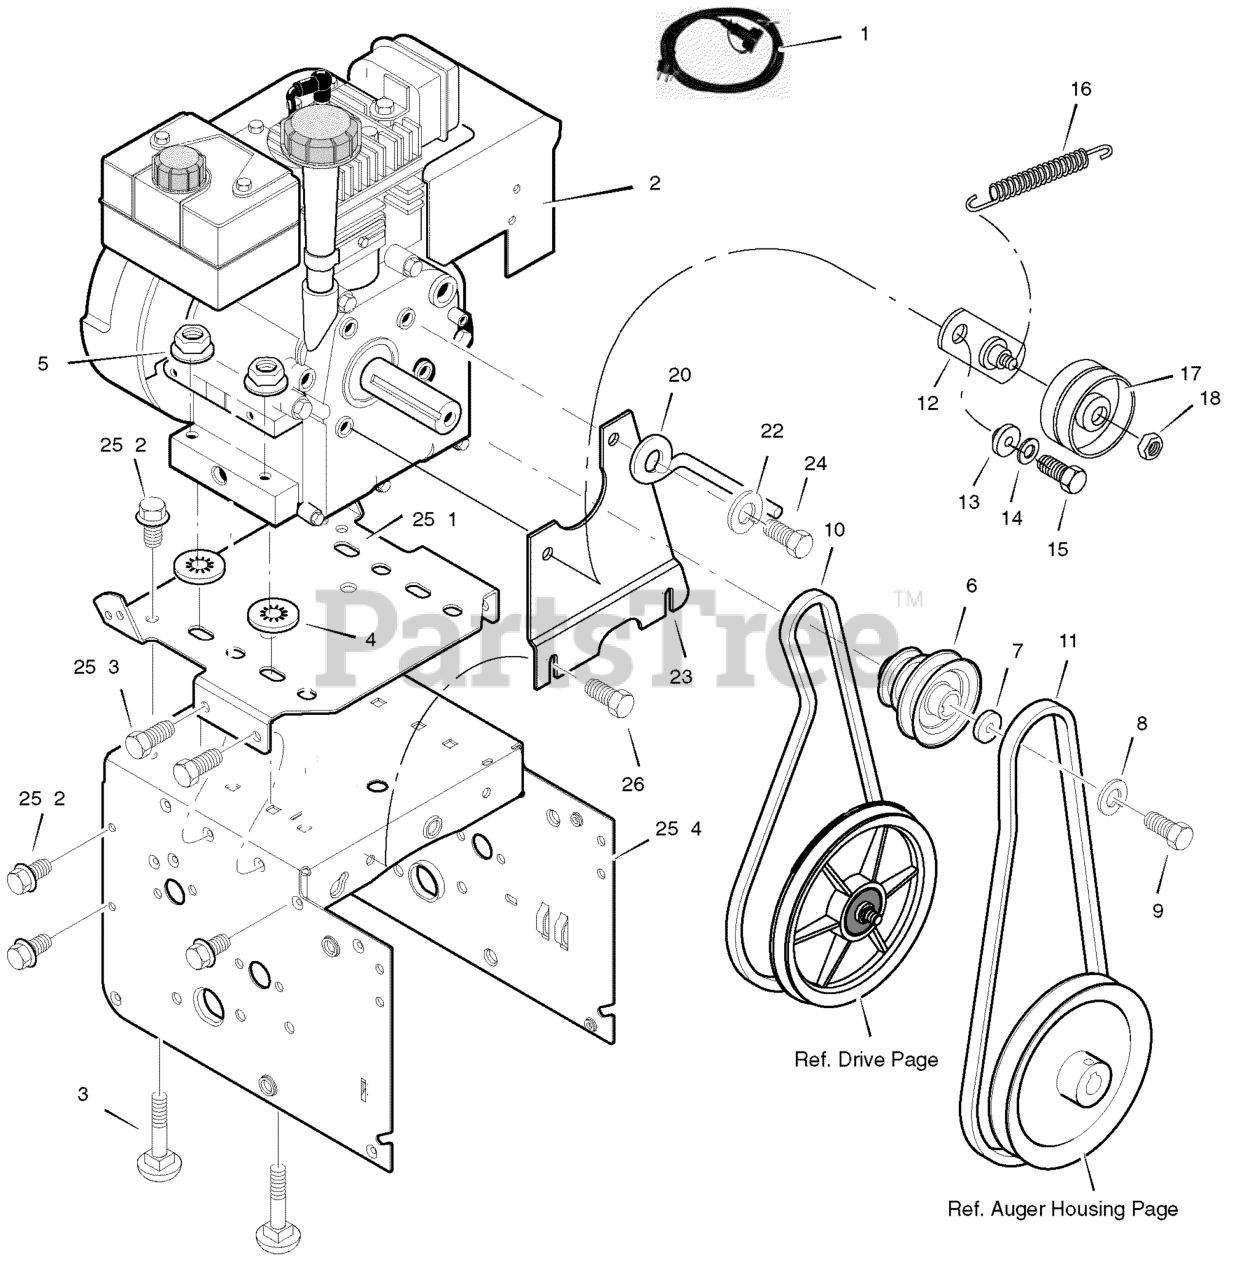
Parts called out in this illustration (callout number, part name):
1	CORD, STARTER
2	ENGINE
3	BOLT, CARRIAGE 5/16-18
4	RETAINER, PUSH
5	NUT 5/16-18
6	PULLEY, ENGINE
7	WASHER
8	WASHER
9	SCREW, 0.37-24X1.00
10	BELT, V 3L
11	BELT, V 4L
12	BRACKET ASSEMBLY, IDLER
13	BUSHING, IDLER BRACKET
14	WASHER
15	SCREW 5/16-24 X 1.00
17	PULLEY, IDLER
18	NUT, JAM 3/8-16
20	GUIDE, ROD BELT
22	WASHER, SPTLK .31X.58X.08
23	PLATE, ANTI VIBRATION
24	SCREW, 5/16-24 x 1.00
25	FRAME ASSEMBLY
26	SCREW
